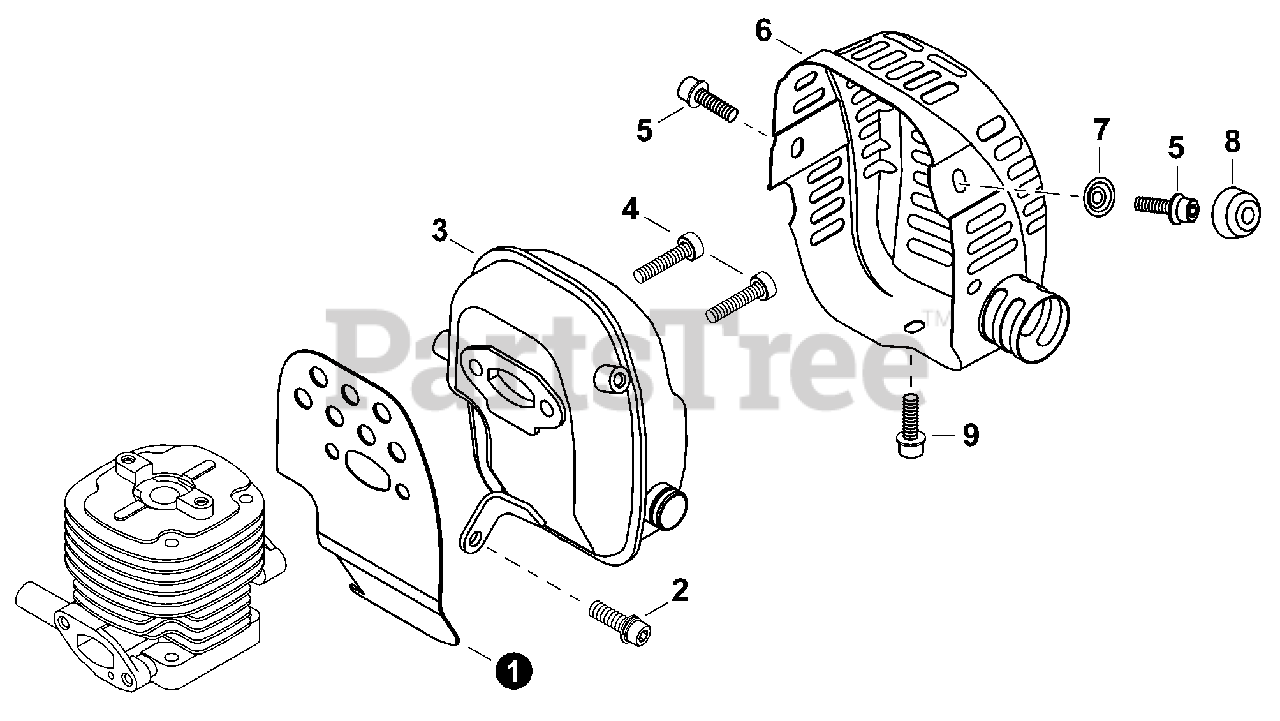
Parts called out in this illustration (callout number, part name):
1	HEAT SHIELD, EXHAUST
2	BOLT M5×12
3	MUFFLER
4	BOLT 6×25
5	BOLT M5×10
6	COVER, MUFFLER
7	WASHER
8	COVER
9	BOLT M5×10
